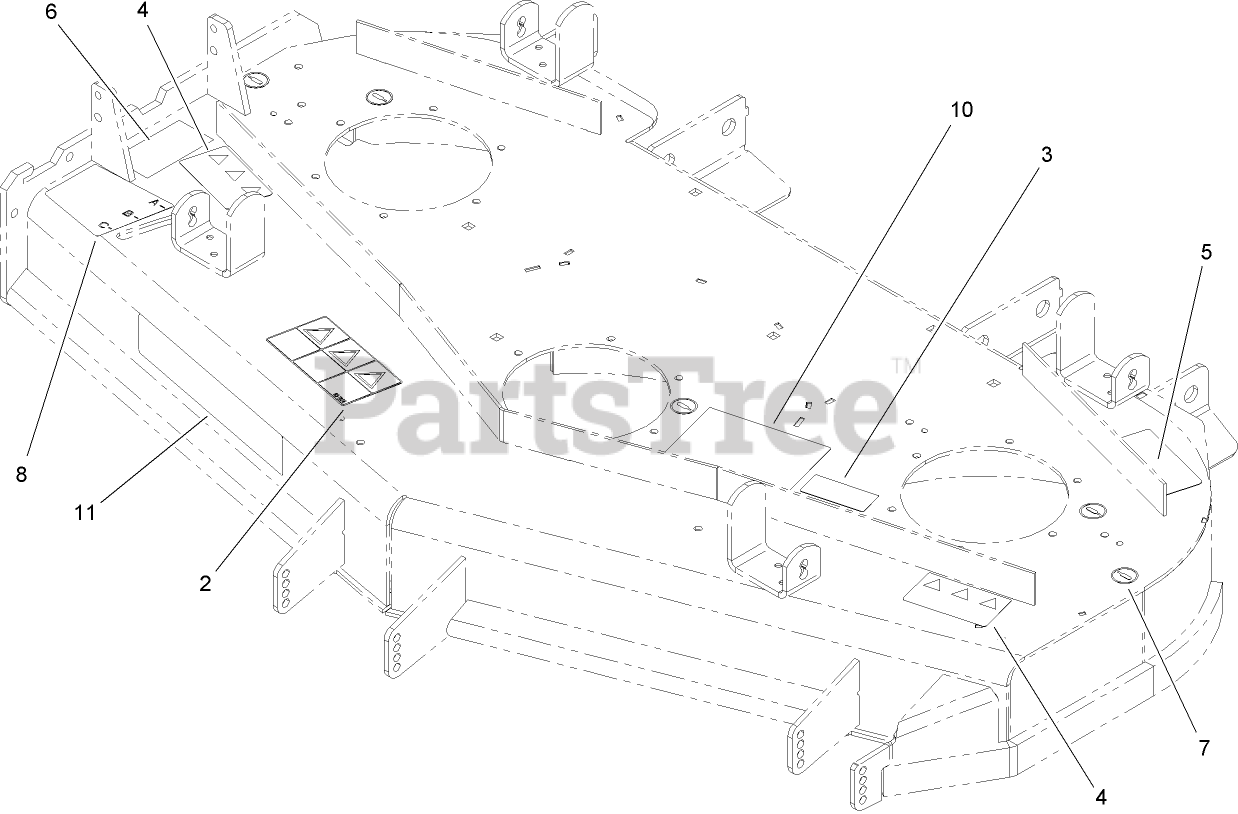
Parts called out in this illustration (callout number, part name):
2	DECAL-DANGER
3	DECAL-WARNING
4	DECAL-DANGER
5	DECAL-TORQUE, BLADE BOLT
6	DECAL-ANTI SCALP
7	DECAL-GREASE
8	DECAL-ADJUSTMENT, BAFFLE
10	DECAL-SERVICE AID
